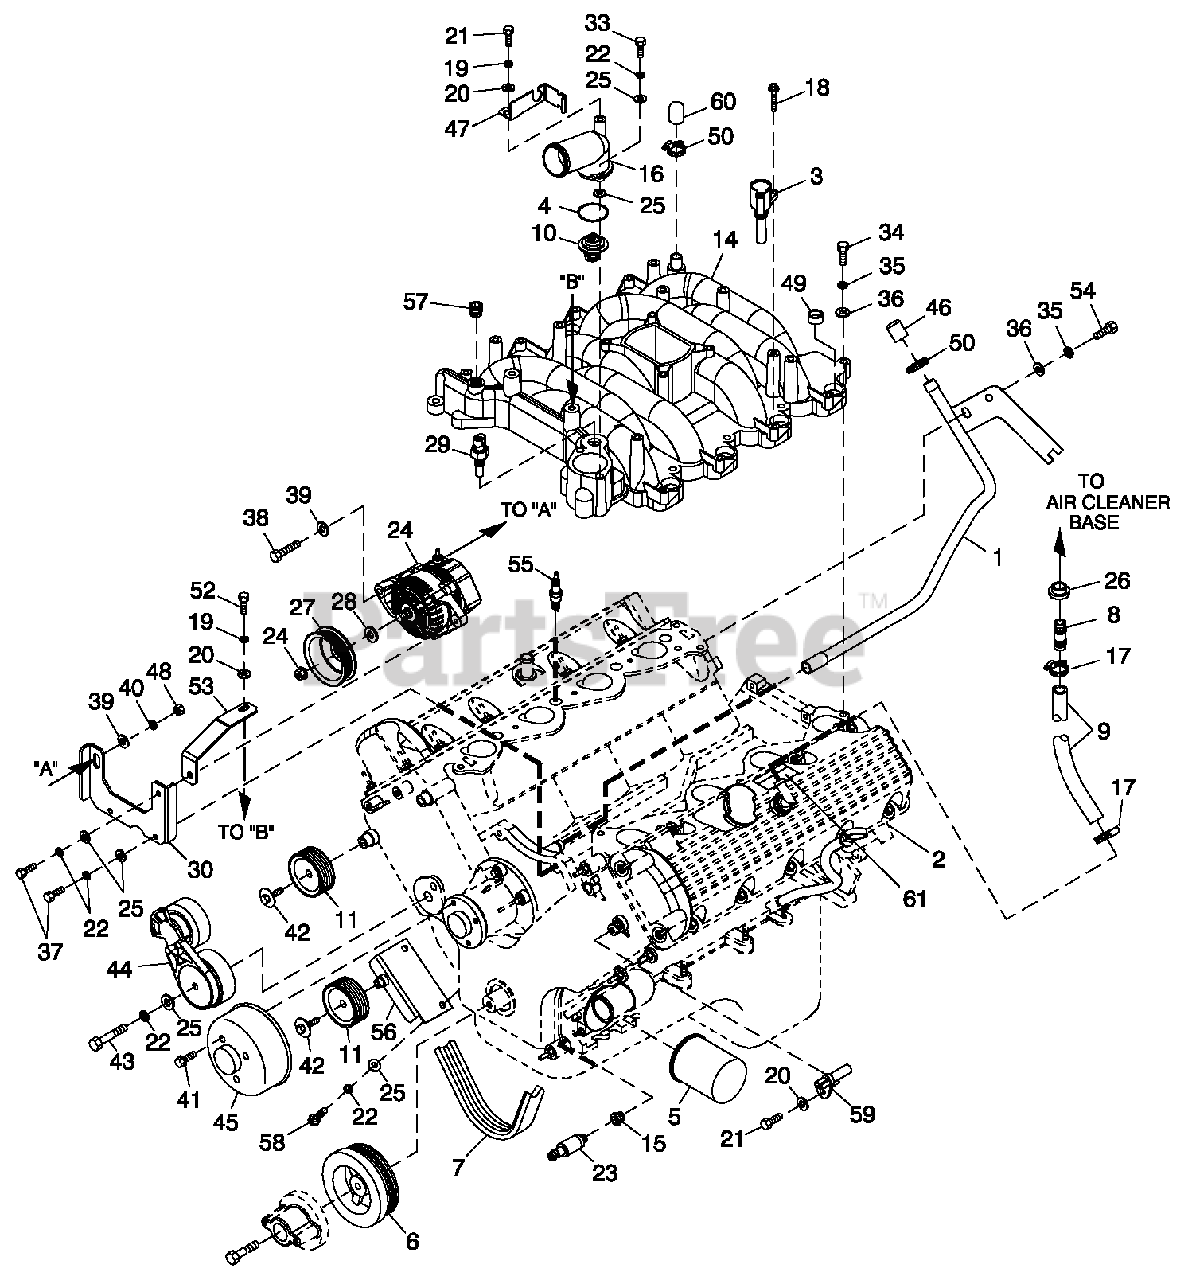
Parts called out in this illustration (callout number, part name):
1	TUBE COOLANT 4.6L (FWD)
2	ENGINE 4.6L G3 (FWD)
3	IGNITION COIL ASSY
4	GASKET THERMOSTAT HOUSING G3
5	OIL FILTER
6	REWORK HARMONIC BALANCER 4.6L
7	BELT SERPENTINE 66.0"
8	BARB CONNECTOR 5/8" HOSE POLYE
9	HOSE COOL 5/8 ID 100R6 (21"LG)
10	THERMOSTAT ASSY
11	PULLEY GROOVED ENGINE IDLER
14	MANIFOLD INTAKE 4.6L G3 (FWD)
15	BSHG RDCR HEX 1/4 TO 1/8
16	CONNECTION WATER OUTLET
17	CLAMP HOSE #8 .53-1.00
18	SCREW SELF TAPPING 25 LONG
19	WASHER LOCK M6-1/4
20	WASHER FLAT 1/4 ZINC
21	SCREW HHC M6-1.0 X 20 G8.8
22	WASHER LOCK M8-5/16
23	SENDER OIL PRESSURE 1/8"NPT
24	ALTERNATOR DC W/OUT PULLEY
25	WASHER FLAT 5/16-M8 ZINC
26	GROMMET 15.87 X 31.75 X 11
27	PULLEY 160 OD DC ALTERNATOR
28	SPACER DC ALTERNATOR PULLEY
29	TEMPERATURE SENDER, DELPHI
30	BRACKET DC ALTERNATOR 4.6L
33	SCREW HHC M8-1.25 X 90 G8.8
34	SCREW HHC M8-1.25 X 50 G8.8
35	WASHER LOCK M8-5/16
36	WASHER FLAT 5/16-M8 ZINC
37	SCREW HHC M8-1.25 X 25 G8.8
38	SCREW HHC M10-1.5 X 45 G8.8 FT
39	WASHER FLAT 3/8-M10 ZINC
40	WASHER LOCK M10
41	SCREW WP PULLEY M8-1.25 X 19
42	BOLT HEX FL HD M8-1.25 X 28
43	SCREW HHC M8-1.25 X 65 G8.8
44	TENSIONER AUTO BELT 4.6L (FWD)
45	PULLEY ENGINE WATER PUMP
46	CAP ANTIFREEZE RUBBER
47	BRACKET, SIGNAL CONDITIONER
48	NUT HEX M10-1.5 G8 YEL CHR
49	PLUG EXPANSION 14 O.D.
50	CLAMP HOSE #10 .56-1.06
52	SCREW HHC M6-1.0 X 16 G8.8
53	ALTERNATOR STRAP
54	SCREW HHC M8-1.25 X 20 G8.8
55	SPARK PLUG (PLATINUM) .044 GAP
56	WELDMENT IDLER BRACKET 4.6L
57	PLUG STD PIPE 3/8 COUNTERSUNK
58	SCREW HHC M8-1.25 X 30 G8.8
59	SENSOR CAM G3
60	CAP RUBBER
61	DECAL EPA STATIONARY EMERGENCY
